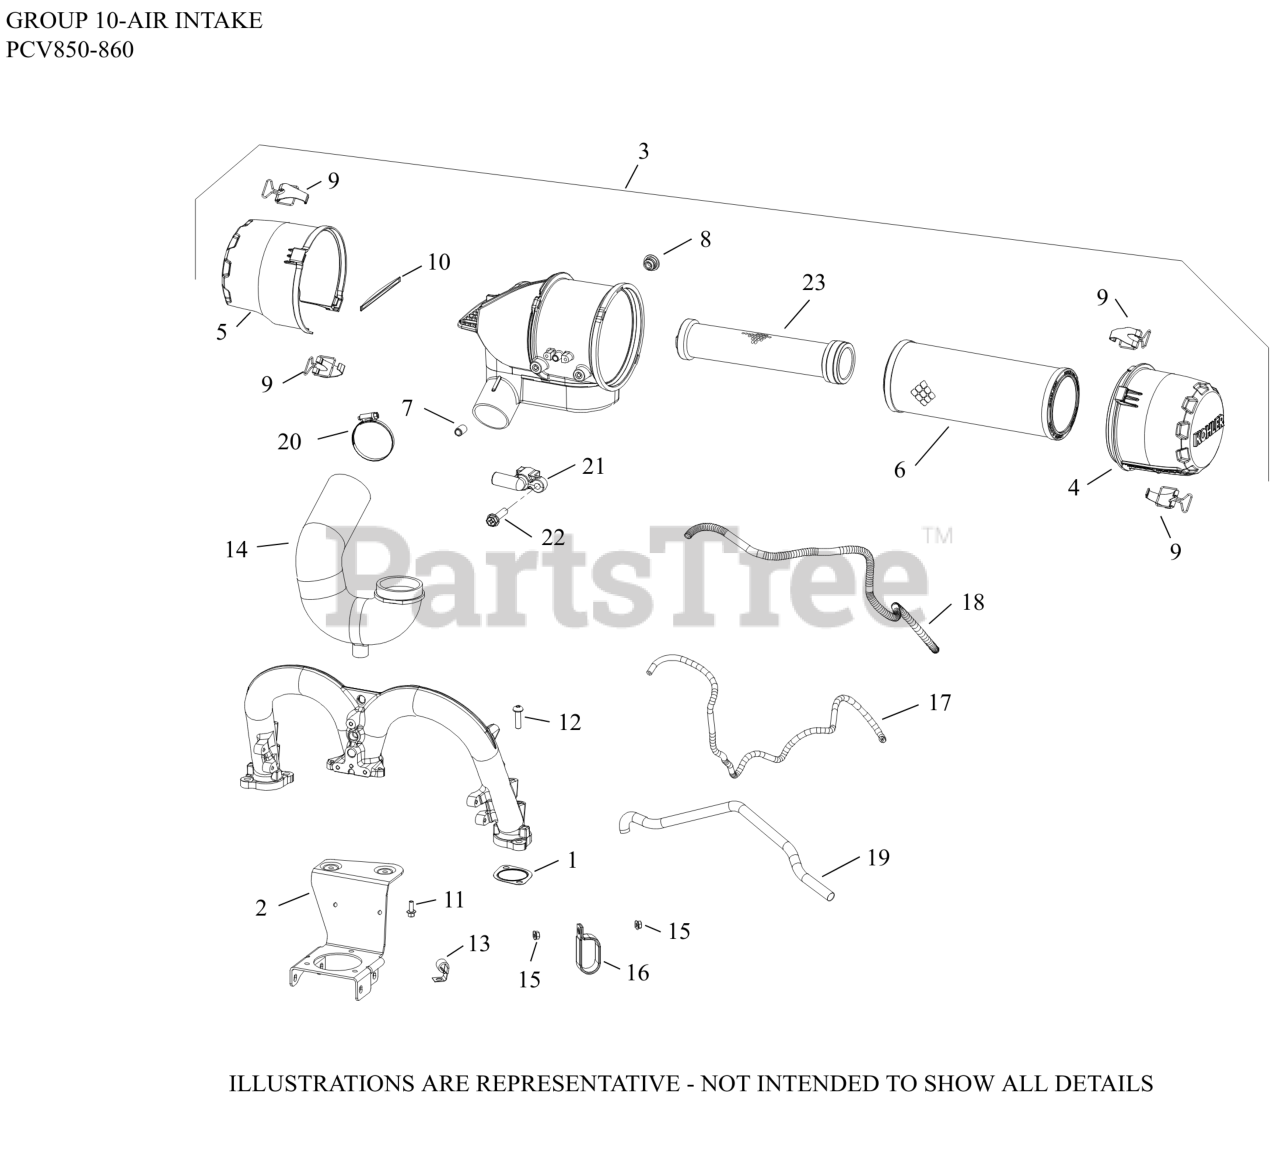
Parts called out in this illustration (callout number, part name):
1	GASKET, INTAKE MANIFOLD
2	BRACKET, HDAC SUPPORT
3	FILTER ASSEMBLY, AIR
4	COVER, AIR FILTER
5	COVER, RAIN CAP
6	ELEMENT, AIR FILTER - PRIMARY
7	CAP, MASKING
8	PLUG, HOLE
9	CLIP ASSEMBLY
10	DAMPER, FOAM INSERT
11	SCREW, FLG M6X1.0X16
12	SCREW, M8 x 30 PAN HD, TORX DRIVE
14	HOSE, AIR CLEANER
16	CLAMP, INSULATED DOUBLE
17	HOSE, EVAPORATIVE
18	SLEEVE, ANTI ABRASION
19	SLEEVE, ANTI ABRASION
20	CLAMP, HOSE
